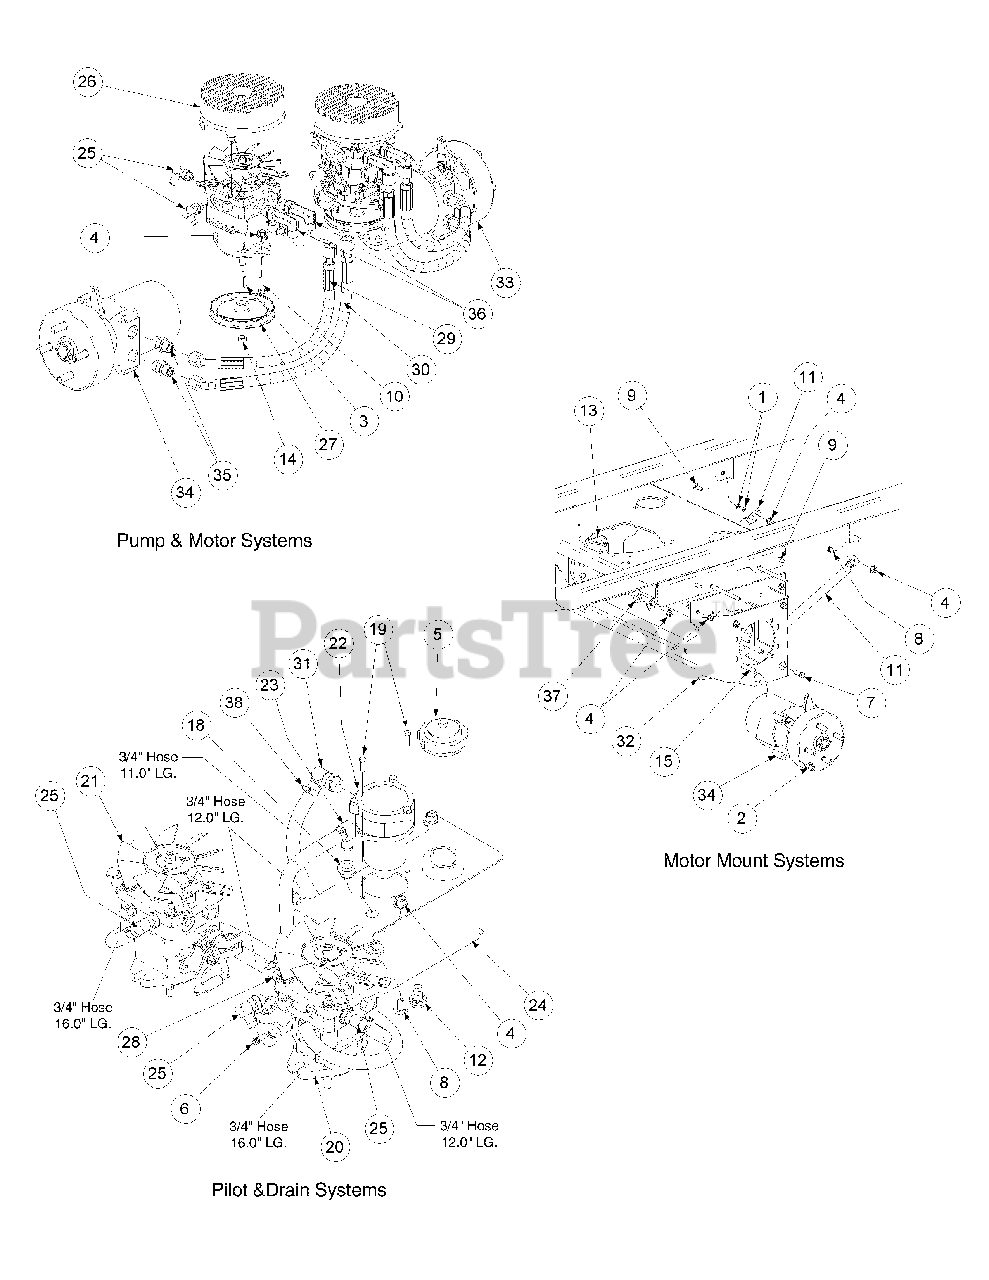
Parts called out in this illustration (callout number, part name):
1	Washer lock 3/8 zinc
2	Washer lock 3/8 zinc
3	Key, 3/16" x 7/8"
4	Flange Lock Hex Nut, 3/8-16
5	Cap, Hydro Oil Tank
6	Hose Clamp
7	Hex Cap Screw, 3/8 -16 x 1.25
8	Carriage Bolt, 3/8-16 x .75 LG.
9	Carriage Bolt, 3/8-16 x 1
10	Carriage Screw, 3/8-16 x 1.25
12	Oil Pan Drain Plug w/ Seal
13	Hydro Wheel Motor Backup Plate
14	Hex Nut, 3/8-24
15	Socket Head Capscrew, 1/2-13; 6-1/2
16	Fuel Hose, .50 ID x .75 OD
17	Carriage Bolt, 3/8-16 x 5.0
18	Grommet Fitting, .54 ID x .78 OD
19	Socket Low Head Cap Screw, 1/4-20 x 0.75
20	Hydro Pump, BDP-12, RH
21	Hydro Pump, BDP-12, LH
22	Hydraulic In-Tank Filter includes:
23	Fitting Elbow Spur, 5/8 x 1/2
24	Hydraulic Tank Assembly
25	Fitting Elbow, 9/16 x 1/2
26	Fan Pump Shroud
27	Hydro Pump Pulley
28	Tee Fitting, 1/2
29	Short Pressure Hose Assembly
30	Long Pressure Hose Assembly
31	Fitting Elbow, 3/4 x 1/2
32	Hydro Motor Frame Assembly
33	Hydro Motor, Left Hand Assembly w/ Brake & Drum
34	Hydro Motor, Right Hand Assembly w/ Brake & Drum
35	Adaptor Fitting, 8 x 10
36	Adaptor Fitting, 8 x 8
37	Spacer .406 ID x 1.0 OD
38	Hose Clamp, 1/2
